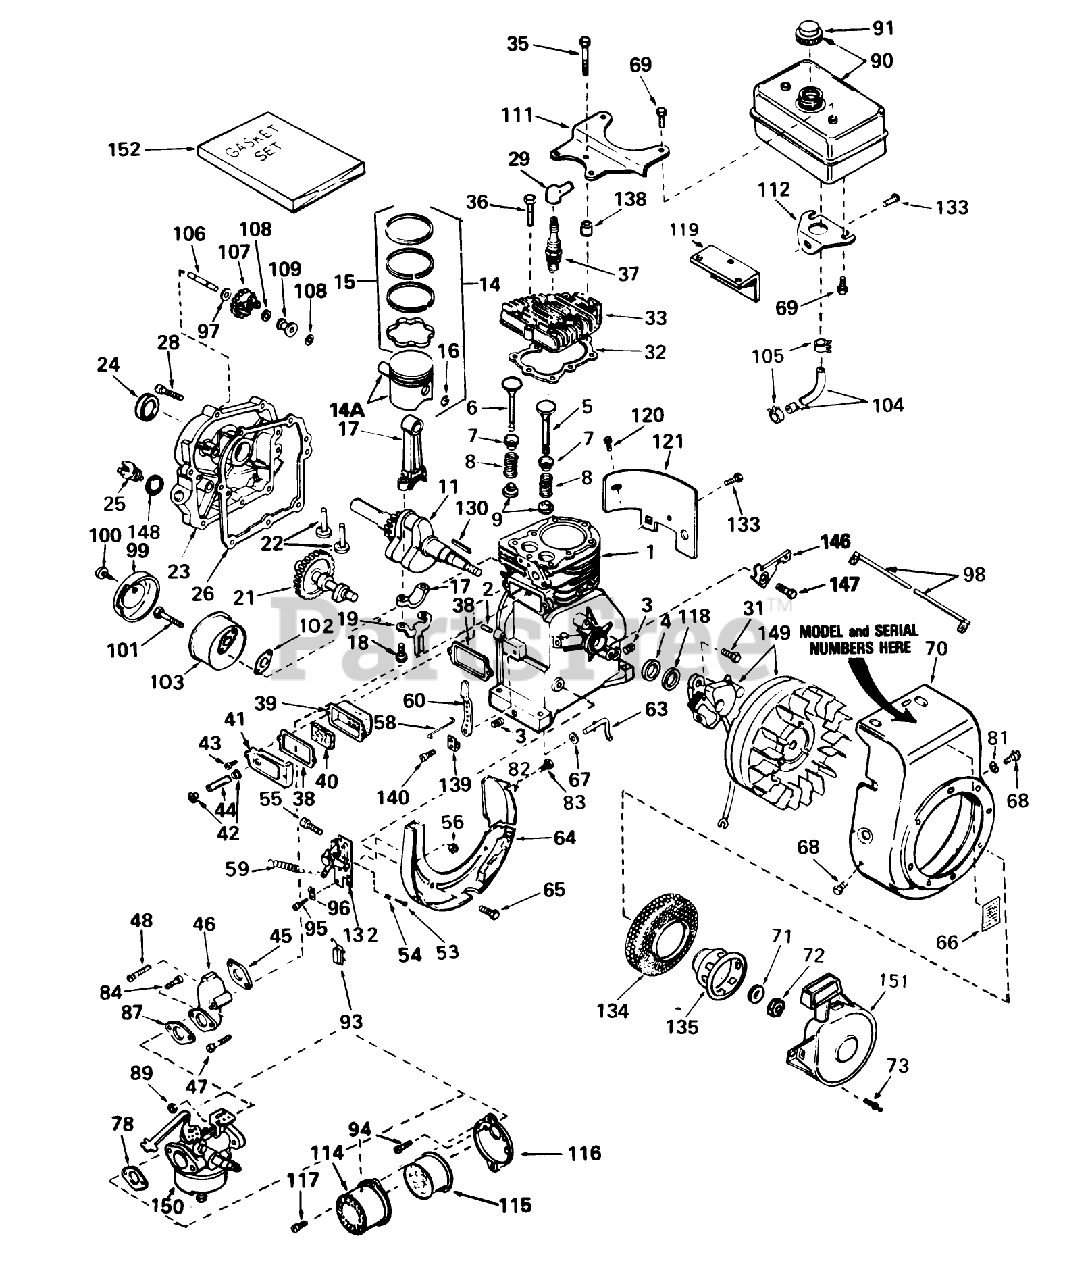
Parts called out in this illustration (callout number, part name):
1	63580 GIL HANDLE BA
2	Pin-Dowel
3	Plug-Drain, Oil (SQH 1/4-18)
4	Seal-Oil
5	Valve, Intake (Incl. Ref. #38, 39 40) (Std.)
5	Valve, Exhaust (1/32" Oversize) (Incl. Nos. 8, 9 10)
6	Valve, Exhaust (Standard) (Incl. Nos. 8, 9 10)
6	Valve, Exhaust (1/32" Oversize) (Incl. Nos. 8, 9 10)
7	Cap-Upper Valve Spring
8	Spring-Valve
9	Cap-Valve, Spring
11	481-1253 SENATOR RO
14	Piston-Pin Ring Assy. (Std.)(Incl. Ref. #14A, 15 16)
14	Piston-Pin Ring Assy. (.010 oversize)(Incl. Ref. #14A, 15 16)
14	Piston-Pin Ring Assy. (.020 oversize)(Incl. Ref. #14A, 15 16)
14A	Piston Pin Assy. (Std)(Incl. Ref. #16)
14A	Piston Pin Assy. (.010 oversize) (Incl. Ref. #16)
14A	Piston Pin Assy. (.020 oversize) (Incl. Ref. #16)
15	Piston Ring Set Std.
15	Piston Ring Set .010 O.S.
15	Piston Ring Set .020 O.S.
16	Ring-Retaining, Piston Pin
17	Rod Assy., Connecting (Incl. Ref. #17)
18	Bolt-Rod, Connecting
19	53020/22 GIL.HYDRO
21	Camshaft (Compression Release
22	Lifter-Valve
23	Cover, Cylinder (Incl. Ref. #24, 25, 106 148)
24	Seal Oil
25	Plug-Fill, Oil
26	Gasket-Cylinder Cover
28	Screw (1/4-20 x 1-1/4)
29	Cover-Spark Plug
31	Screw
32	Gasket-Cylinder Head
33	CYLINDER HEAD
35	Screw (5/16-18 X 2)
36	Screw (5/16-18x1-1/2)
37	Plug, Spark (J17LM or equiv.)
37	Plug, Spark (Champion RCJ-8)
38	Gasket-Breather
39	Body-Breather
40	Element-Breather
41	Cover-Breather
42	GROMMET
43	Screw
44	Breather Tube
45	Gasket-Intake
46	Pipe, Intake
47	Screw (1/4-20 x 1-19/32)
48	Screw
53	Screw
54	Spring-Compression
55	Screw, Fil. Hd.
56	Nut Lockwasher Assy.
58	Jet-Main
59	Spring-Extension
60	Lever-Governor
63	Rod-Governor
64	Baffle-Blower Housing
65	Screw (1/4-20x19/32)
66	Decal, Instruction
67	Washer-Flat
68	Screw
69	Screw (1/4-15x7/8)
70	Housing, Blower
71	Washer-Belleville
72	Nut-Flywheel
73	Rivet, Pop (Can be purchased locally)
78	Gasket
81	Washer
82	Baffle-Extension
83	Screw-Hex Washer Hd.
87	Gasket
89	Nut and Lock Washer (1/4-28)
90	481-1261 SENATOR TI
91	Cap, Fuel
93	Terminal
94	Screw (10-32 x 1/2)
95	Screw (10-32 x 3/8)
96	Conduit
97	Washer-Flat
98	Wire-Ground
99	Cover-Muffler
100	Screw (1/4-15x7/8)
101	Screw
102	Gasket Exhaust
103	Muffler
104	Line-Fuel
105	Clamp-Line, Fuel
106	Shaft-Governor
107	Governor Gear ASM
108	Ring-Retaining
109	Spool-Governor
111	Plate-Fuel Tank
112	Bracket-Fuel Tank
114	Body-Air Cleaner
115	AIRCLEANER
116	BRACKET, AIRCLEANER
117	Screw
118	Gasket Stator
119	Baffle-Heat
120	Screw
121	Extension-Blower
130	Key-Flywheel
132	Bracket Assy., Control (Incl. Ref. #149 thru 152 154)
133	Screw (1/4-20x19/32)
134	Screen-Starter
135	Cup-Starter
138	pacer
139	Clamp-Lever, Governor
140	Screw
146	Bracket-Hold Down
147	Screw (10-24 x 9/16)
148	Gasket
149	Magneto (The complete magneto is not available as an assembly. The magneto number is shown for reference purposes only. Order component parts individually, as shown in parts list.)
150	Carburetor (Incl. Ref. #87)
151	Starter, Rewind
152	Gasket Set (Incl. items marked*
